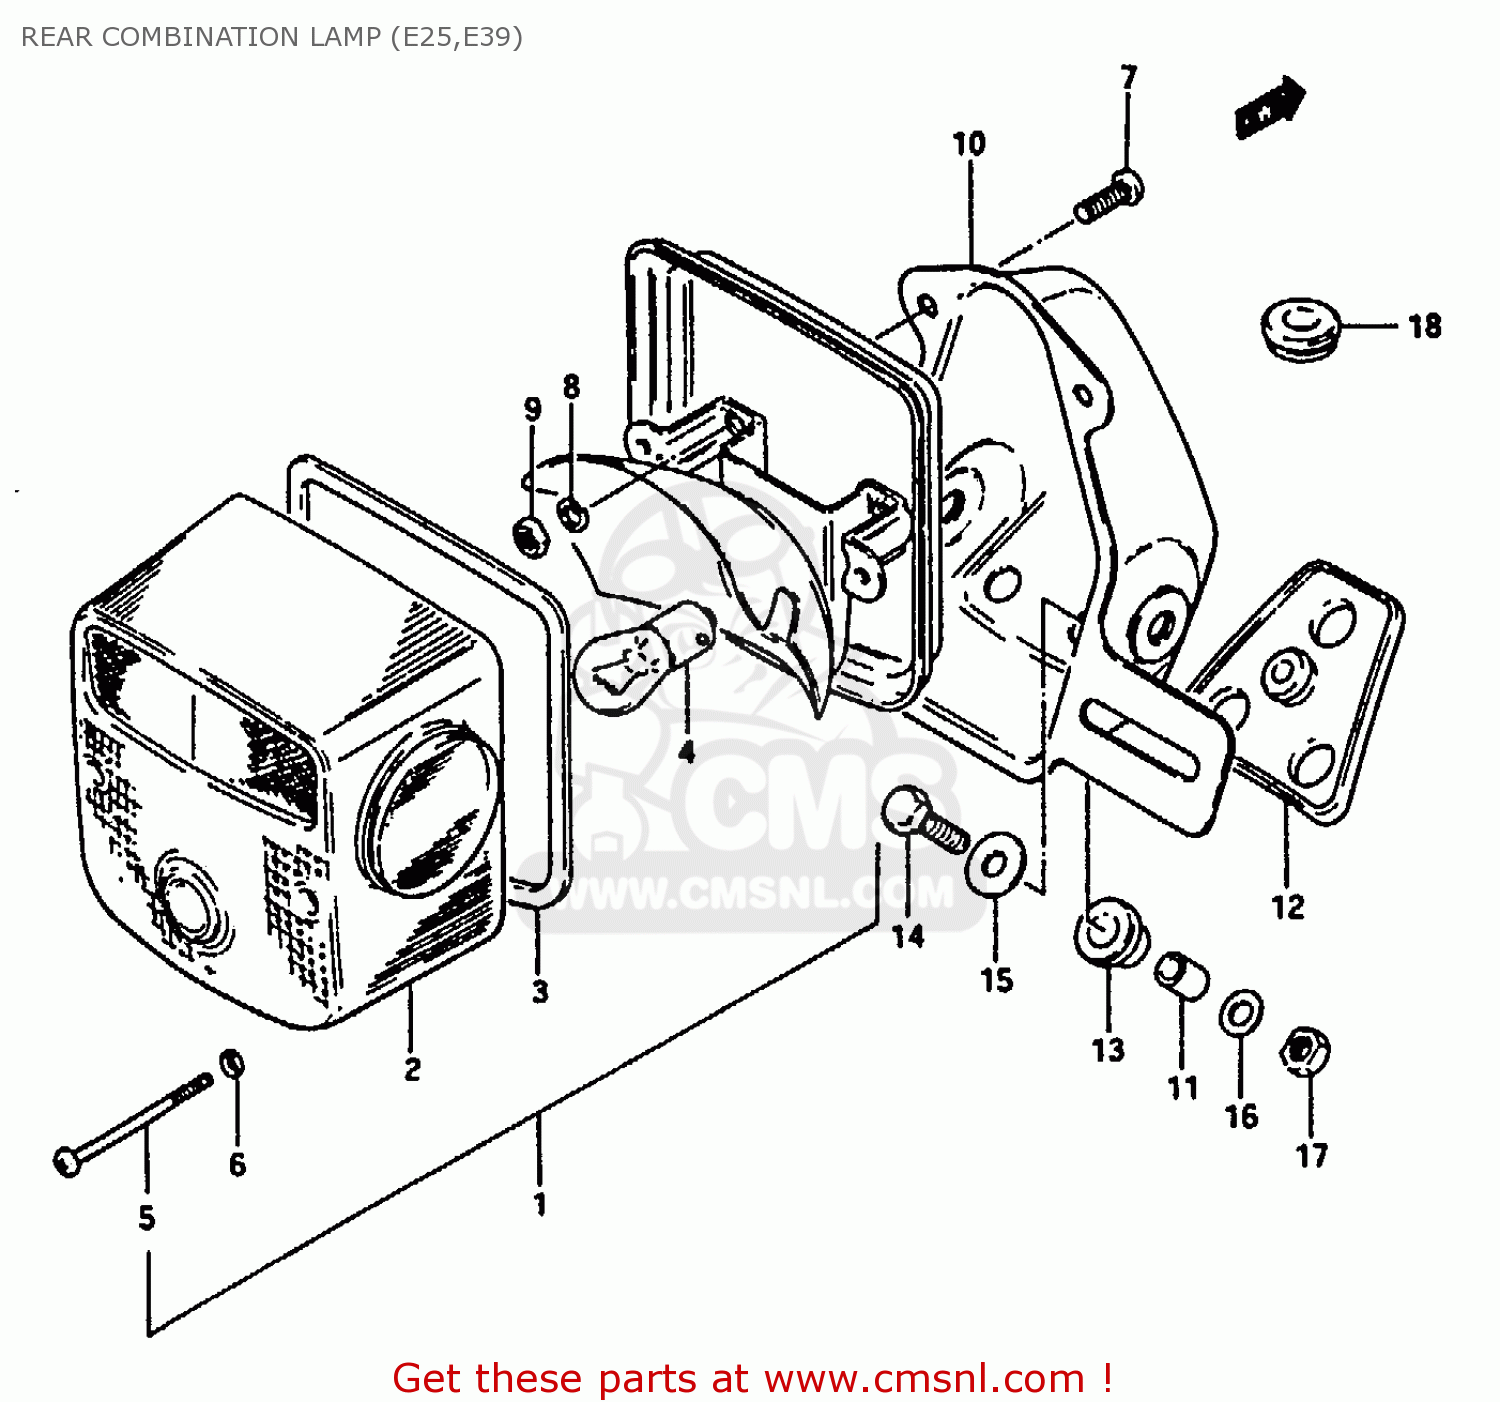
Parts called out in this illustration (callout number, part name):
1	LAMP UNIT,RR COMBNATION
2	LENS
3	GASKET (NAS)
4	BULB 12V21/5W
5	SCREW (4X55)
6	GASKET (NAS)
7	SCREW
8	WASHER,LOCK
9	NUT
10	BRACKET UNIT,TAIL LAMP
11	SPACER
12	CUSHION
13	CUSHION
14	BOLT
15	WASHER (6.5X20X1.2)
16	WASHER
17	NUT 6MM
18	GROMMET
